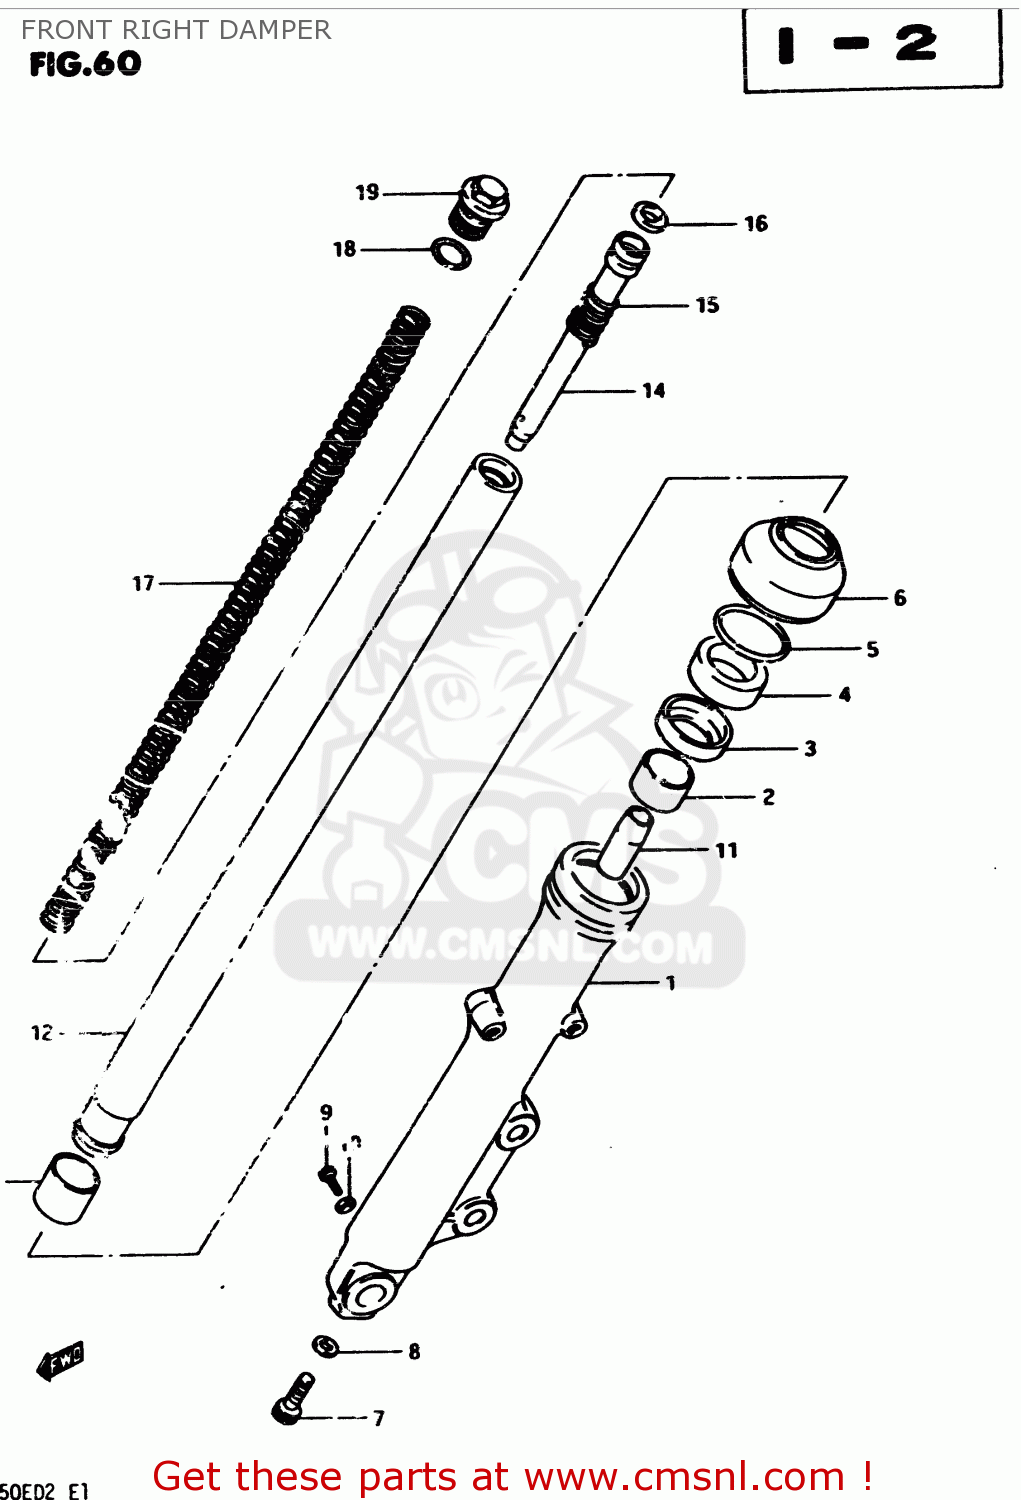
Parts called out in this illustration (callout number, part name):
1	OUTER TUBE RH
2	BUSH,GUIDE
3	SPACER,OIL SEAL
4	OIL SEAL,FRONT FORK
5	CIRCLIP,FORK OIL SEAL
6	DUST SEAL
7	BOLT(8X27)
8	GASKET (NAS)
9	BOLT
10	GASKET,DRAIN,PLUG (NAS)
11	PIECE,OIL LOCK
12	TUBE,INNER
13	BUSH
14	CYLINDER,FRONT FORK
15	SPRING,REBOUND
16	RING,PISTON
17	SPRING,FR.FORK
18	O RING
19	BOLT
